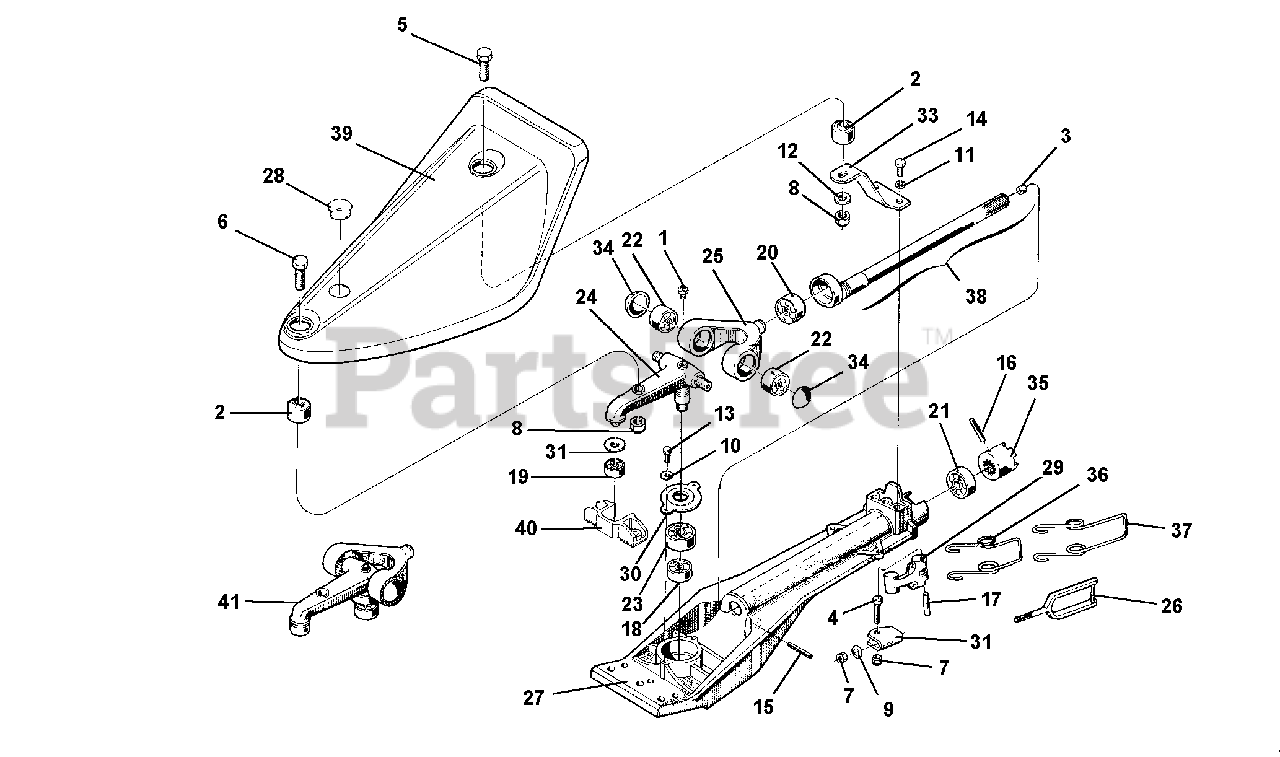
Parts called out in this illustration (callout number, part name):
1	LUBRICATOR M10
4	SCREW TE M8 X 30
5	SCREW M10 X 45
6	SCREW M10 X 60
7	NUT, SELF LOCKING M8
8	NUT, SELF LOCKING M10
9	SUPER WASHER 8 DIN 6796
10	WASHER, LOCK 6.4
11	WASHER, LOCK 8.4
12	WASHER, LOCK 10.5
13	SCREW M6 X 12
14	SCREW M8 X 15
15	PIN, LOCKING 5 X 40
16	PIN, LOCKING 6 X 40
17	SPIRAL PIN 8 X 40
18	BEARING 12 X 37 X 12 6301
19	BEARING 62200-2RS-10 X 30 X 14
20	BEARING SKF 17 X 40 X 12 6203 ST
21	BEARING 20 X 42 X 12 6004 2RS
22	BEARING 15 X 35 X 11
22	BEARING 6202 Z 15 X 35 X 11
23	BEARING 6204 Z 20 X 47 X 14
24	BLADE CONTROL CRANK
28	PLUG FOR D 26 HOLE
30	BEARING COVER
31	IMPLEMENT HOOK COUPLING
32	PROTECTION WASHER
33	ELASTIC CONNECTION
34	BOTTOM PLUG
35	BAR COUPLING
37	LONG SPRING HOOK
38	SHAFT WITH BUSH
39	OSCILLATING PROTECTION
40	BLADE COUPLING
41	CRANK WITH COVER
